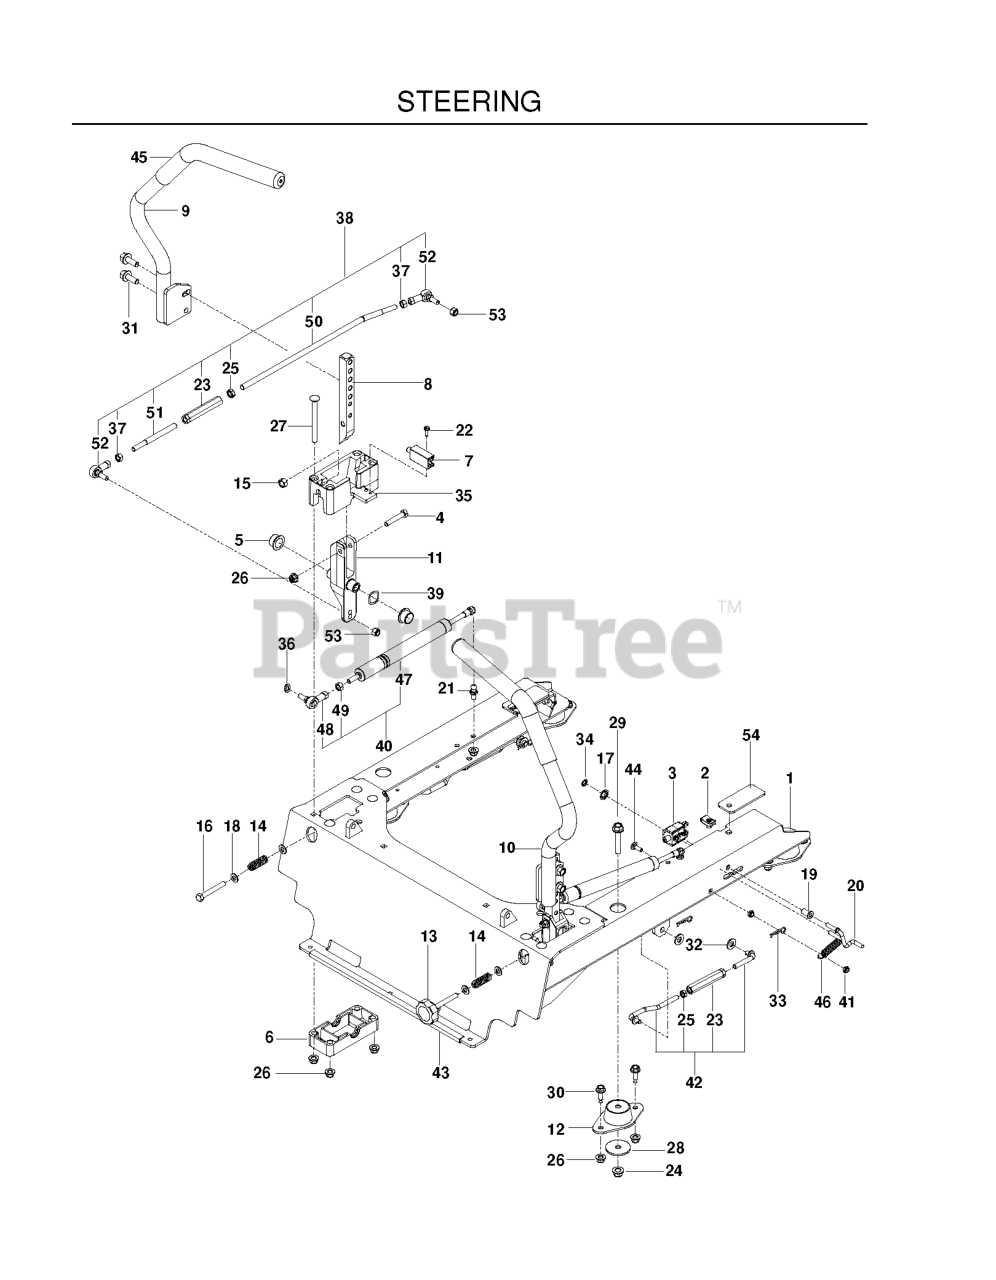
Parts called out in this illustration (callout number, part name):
1	FRAME.SEAT.MOUNT.ORANGE
2	U-CLIP 5/16-18 NUT RETAINER
3	SWITCH, BRAKE 3P
4	HCS 5/16C X 1 3/4
5	BEARING, FLANGE
6	BLOCK, LOWER
7	SWITCH, INTERLOCK
8	LEVER, MOTION
9	LEVER, W/GRIP, RT
10	LEVER, W/GRIP, LT
11	LEVER, CONTROL
12	MOUNT, ISO
13	KNOB
15	NUT 5/16C HEX
16	HCS 5/16-18 X 2 1/2 TPBLT
17	NUT 3/8 PALNUT RTNG BLK PHOS
18	FLAT WASHER 5/16 SAE
19	BUSHING, 1/4 FLANGE
20	LINK, SWITCH
21	STUD.BALL.10MM
22	SCREW #10 X 1/2 SELF TAPPING
23	TURNBUCKLE, 3/8
24	NUT 3/8-16 HEX FLG NYLOC ZD
25	NUT 3/8-24 JAM
26	5/16-18 NYLOC FLANGE NUT
27	RHSNB 5/16-18 X 3-3/4 GR 5 ZD
28	WASHER, 3/8 SPEC
29	HHFS 3/8-16 X 2.0 GD 5
30	HHFS 5/16-18 X 3/4
31	HHFS 3/8-16 X 1 GRD 5 ZD
32	WASHER 3/8 SAE FLAT
33	HAIRPIN #2
34	NUT PUSH
35	BLOCK, UPPER
36	WASHER.LOCK.HVY.HLCL.SPR.5/16
38	LINKAGE, CONTROL, DIESEL
39	WASHER, .825 X 1.087, WAVE
40	ASSEMBLY, DAMPENER
41	JAM NUT 1/4C (2 2 PW01)
42	ASSEMBLY, SEAT STRUT
43	RP.FLEX TRIM, BLK-LENGTH 1 FT
44	RHSNB 1/4C X 3/4
45	GRIP - DRIVE LEVER 12"
46	SPRING, EXTENSION
49	NUT M8 X 1.25 STD HEX
50	LINKAGE, CONTROL, FT
51	LINKAGE, CONTROL
52	SPHERICAL ROD END, RH
53	NUT 5/16F NYLOC
54	SPACER, BLK
